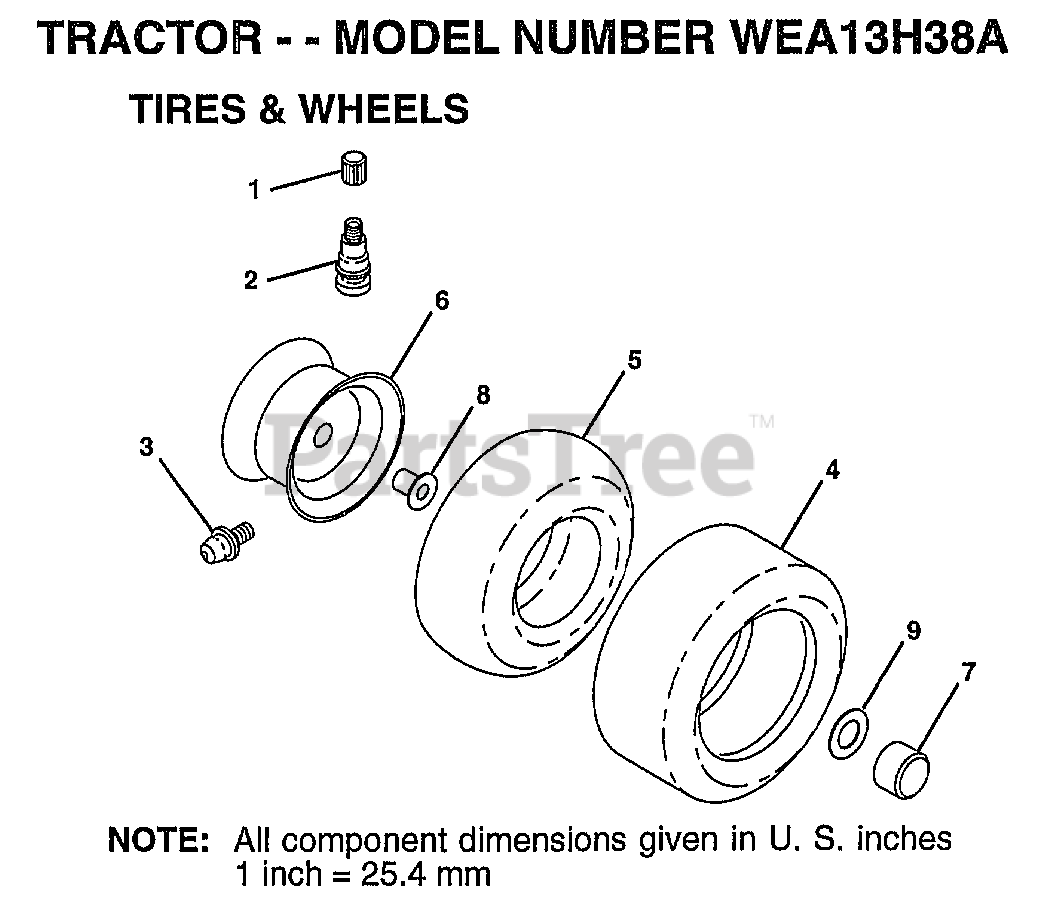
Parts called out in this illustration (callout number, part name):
1	VALVE CAP
2	VALVE STEM LT
3	FITTING LT
5	TUBE.5.3/4.5/6
5	TUBE.16X6.5/7.5-8
6	"RIM FRONT 6"""
6	"RIM ASM REAR 8"""
7	HUB CAP
8	"FLANGE, BEARING"
9	WASHER
